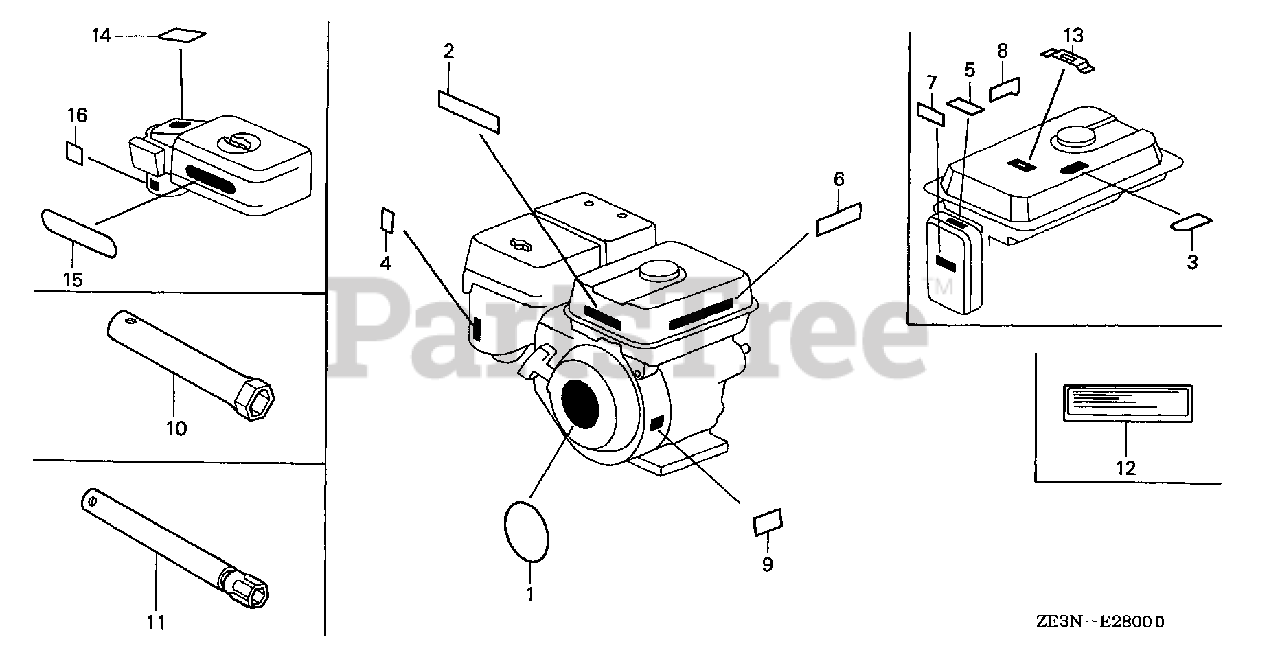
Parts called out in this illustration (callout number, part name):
1	EMBLEM
2	LABEL, CAUTION
6	MARK, OIL ALERT (E)
9	MARK, OIL ALERT (E)
14	LABEL, AIR CLEANER CAUTION
15	MARK, AIR CLEANER SALES POINT
16	MARK, CHOKE (EXTERNAL)
